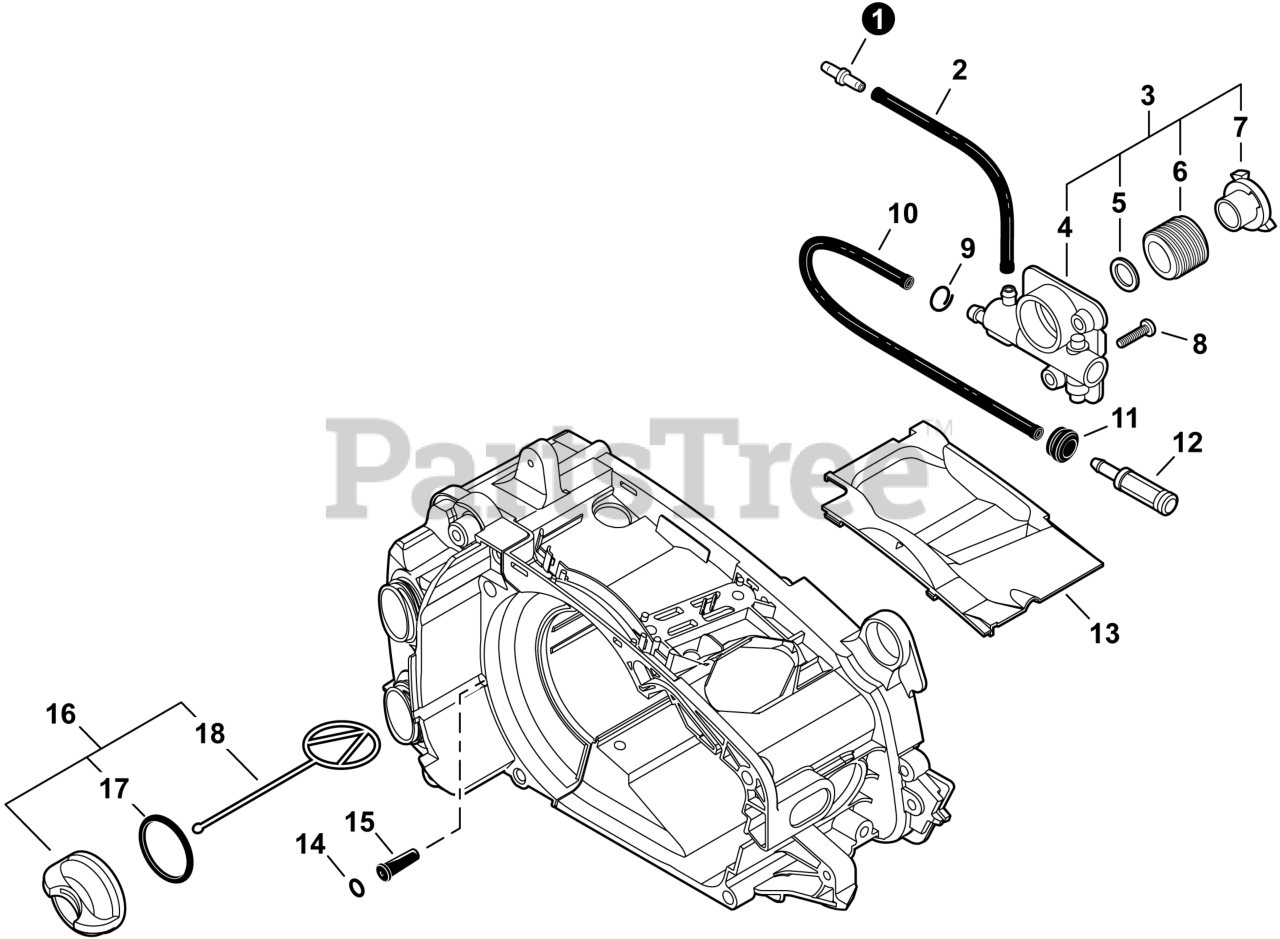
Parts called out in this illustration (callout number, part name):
1	CONNECTOR, PIPE
2	PIPE, 3x6x45 BLACK
3	AUTO-OILER ASSY
4	AUTO-OILER
5	WASHER 10.5x17.4x1.8
6	GEAR, WORM
7	COLLAR 10
8	BOLT, TORX 4x12
9	CLIP 6.5 MM
10	PIPE 3x6x160
12	FILTER, OIL
13	COVER, DUST
14	O-RING S-4
15	VENT ASSY
16	CAP ASSY - BLACK
17	O-RING 18
18	CONNECTOR, CAP L= 60 MM
